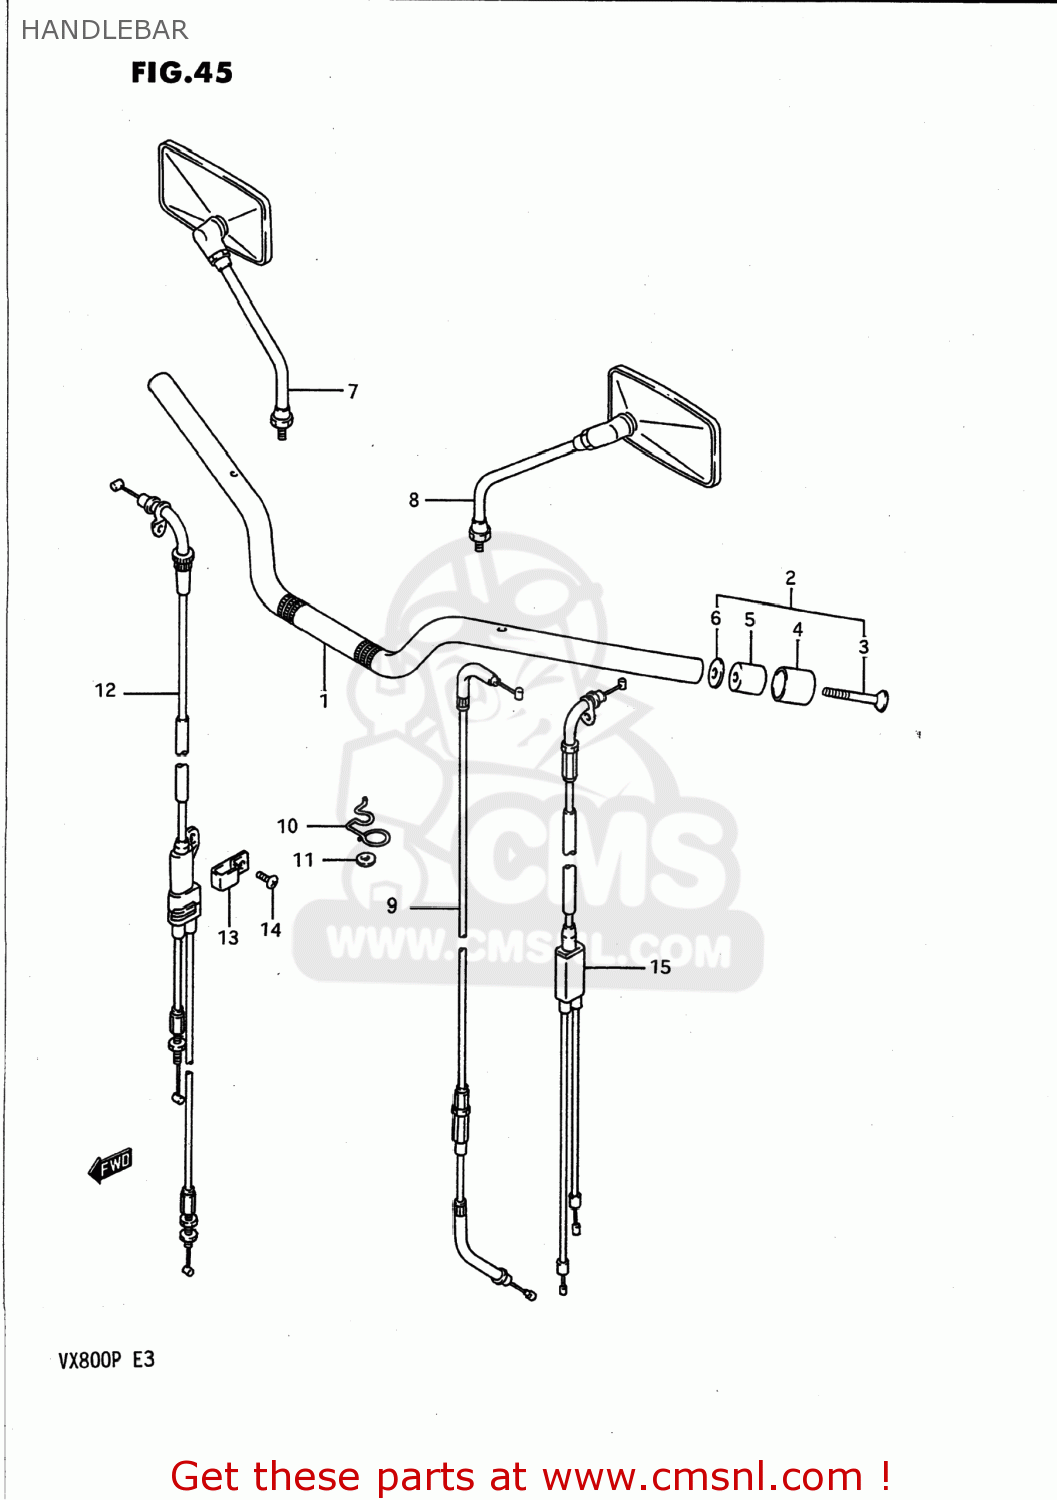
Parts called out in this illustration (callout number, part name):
1	HANDLEBAR
2	BALANCER SET,HANDLEBAR
3	SCREW 6X65
4	CAP,BALANCER
5	BALANCER,HANDLEBAR
6	SPACER,BALANCER
7	MIRROR ASSY,RR VIEW,R
8	MIRROR ASSY,RR VIEW,L
9	CABLE ASSY,CLUTCH
10	GUIDE,CLUTCH CABLE
11	WASHER
12	CABLE ASSY,THROTTLE
13	CLAMP,THROTTLE CABLE
14	SCREW,THROTTLE CABLE
15	CABLE,STARTER
